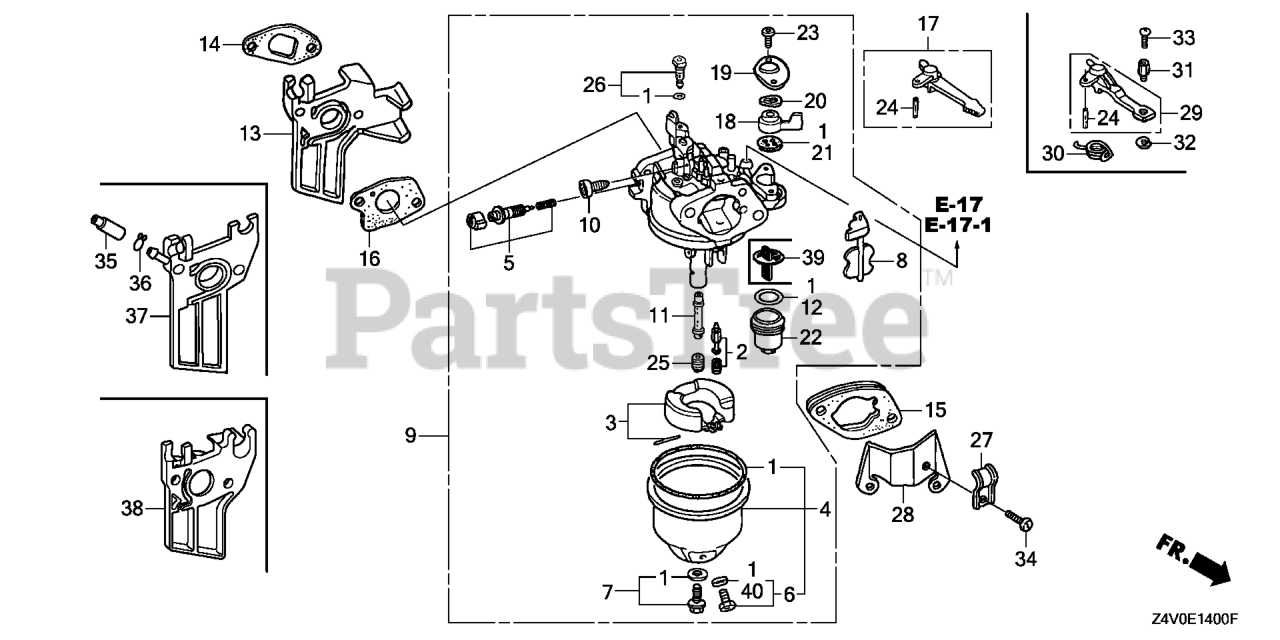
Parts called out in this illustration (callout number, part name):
1	GASKET SET
2	VALVE SET, FLOAT (CARBURETOR NO.) (SEAT NOT INCLUDED)
3	FLOAT SET
4	CHAMBER SET, FLOAT
5	SCREW SET (CARBURETOR NO.)
6	SCREW SET, DRAIN
7	SCREW SET (CARBURETOR NO.)
8	CHOKE SET (CARBURETOR NO.)
9	CARBURETOR ASSY. (BEA3P A)
10	SCREW, THROTTLE STOP
11	NOZZLE, MAIN (CARBURETOR NO.)
12	GASKET, FUEL STRAINER CUP
14	GASKET, INSULATOR
15	SPACER, CARBURETOR
16	GASKET, CARBURETOR
17	LEVER, CHOKE (STD)
18	LEVER, VALVE
19	PLATE, LEVER SETTING (CARBURETOR NO.)
20	SPRING, PETCOCK LEVER (CARBURETOR NO.)
21	GASKET, VALVE
22	CUP, FUEL STRAINER
23	SCREW, PAN (3X6)
24	PIN, SPRING (2X12)
25	JET, MAIN (#75) (CARBURETOR NO.)
25	JET, MAIN (#78) (CARBURETOR NO.)
25	JET, MAIN (#80)
26	JET SET, PILOT (#40) (ADVENTURE GREEN) (CARBURETOR NO.)
38	INSULATOR, CARBURETOR
39	FILTER, CUP (CARBURETOR NO.)
40	WASHER, PLAIN (6.2X10.7 DRAIN) (CARBURETOR NO.)
